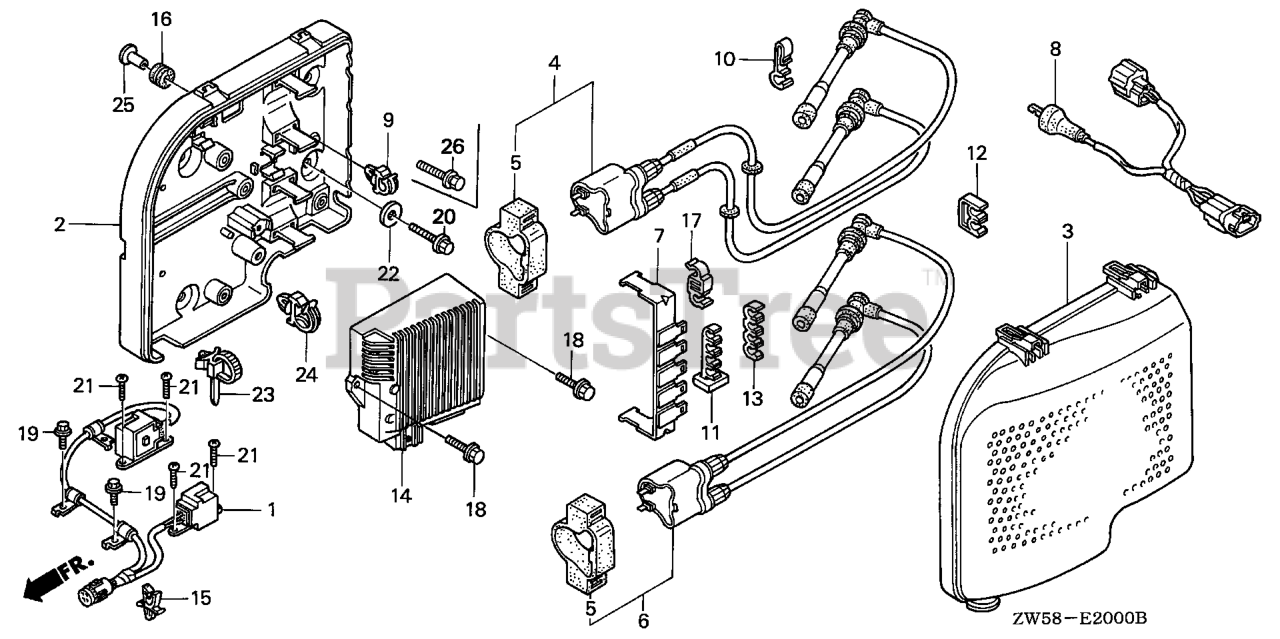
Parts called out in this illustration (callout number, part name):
1	COIL ASSY., PULSER
2	CASE, IGNITION CONTROL MODULE (CDI)
3	COVER, IGNITION CONTROL MODULE (CDI)
4	COIL ASSY., IGNITION (1,4)
5	SUSPENSION, IGNITION COIL
6	COIL ASSY., IGNITION (2,3)
7	BRACKET, CONNECTOR (A)
8	WIRE, SWITCH
9	CLAMP, WIRE
10	CLAMP, WIRE
11	CLAMP A, IGNITION WIRE
12	CLAMP B, IGNITION WIRE
13	GROMMET, IGNITION WIRE
14	CONTROL UNIT, ELECTRONIC
15	CLIP B, AIR TEMPERATURE SWITCH (Honda Code 1610054). WIRE
16	GROMMET, CASE (LOWER)
17	CLIP A, WATER VALVE SOLENOID
18	BOLT, FLANGE (6X16)
19	BOLT, FLANGE (6X12)
20	BOLT, FLANGE (6X25)
21	SCREW, PAN (5X14)
22	WASHER, PLAIN (6MM)
23	STRAP, CABLE (118MM) *NH1L* (Honda Code 1170653). (BLACK)
24	CLIP, WIRE HARNESS
25	COLLAR, MODULE IGNITION CONTROL CASE (CDI)
